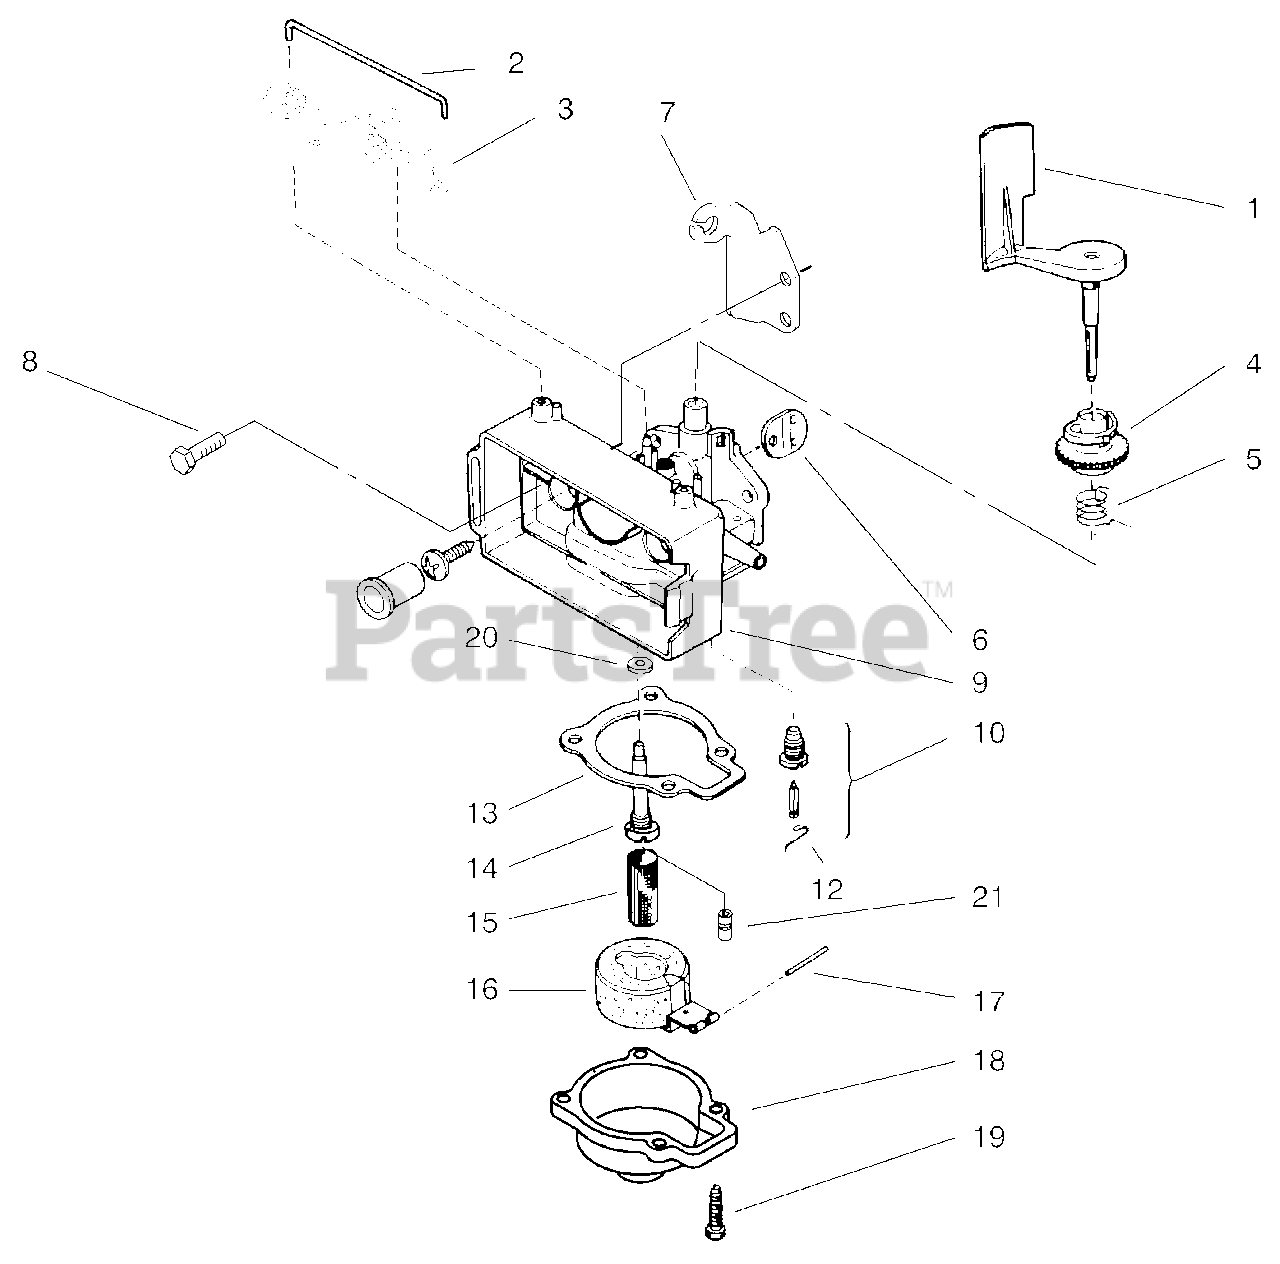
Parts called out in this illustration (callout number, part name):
1	Air Vane & Shaft
2	Retainer-Speed Control
3	Lever-Speed Adjust
4	Collar-Air Vane
5	Spring-Governor
6	Disc-Throttle
7	Bracket-Throttle Control
9	Carburetor Body
10	Kit-Float Valve, Body & Seat (Incl. Ref. #12)
12	Spring
13	Gasket
15	Filter-Fuel
16	Float & Arm Assembly
18	Float Chamber
21	Main Jet
